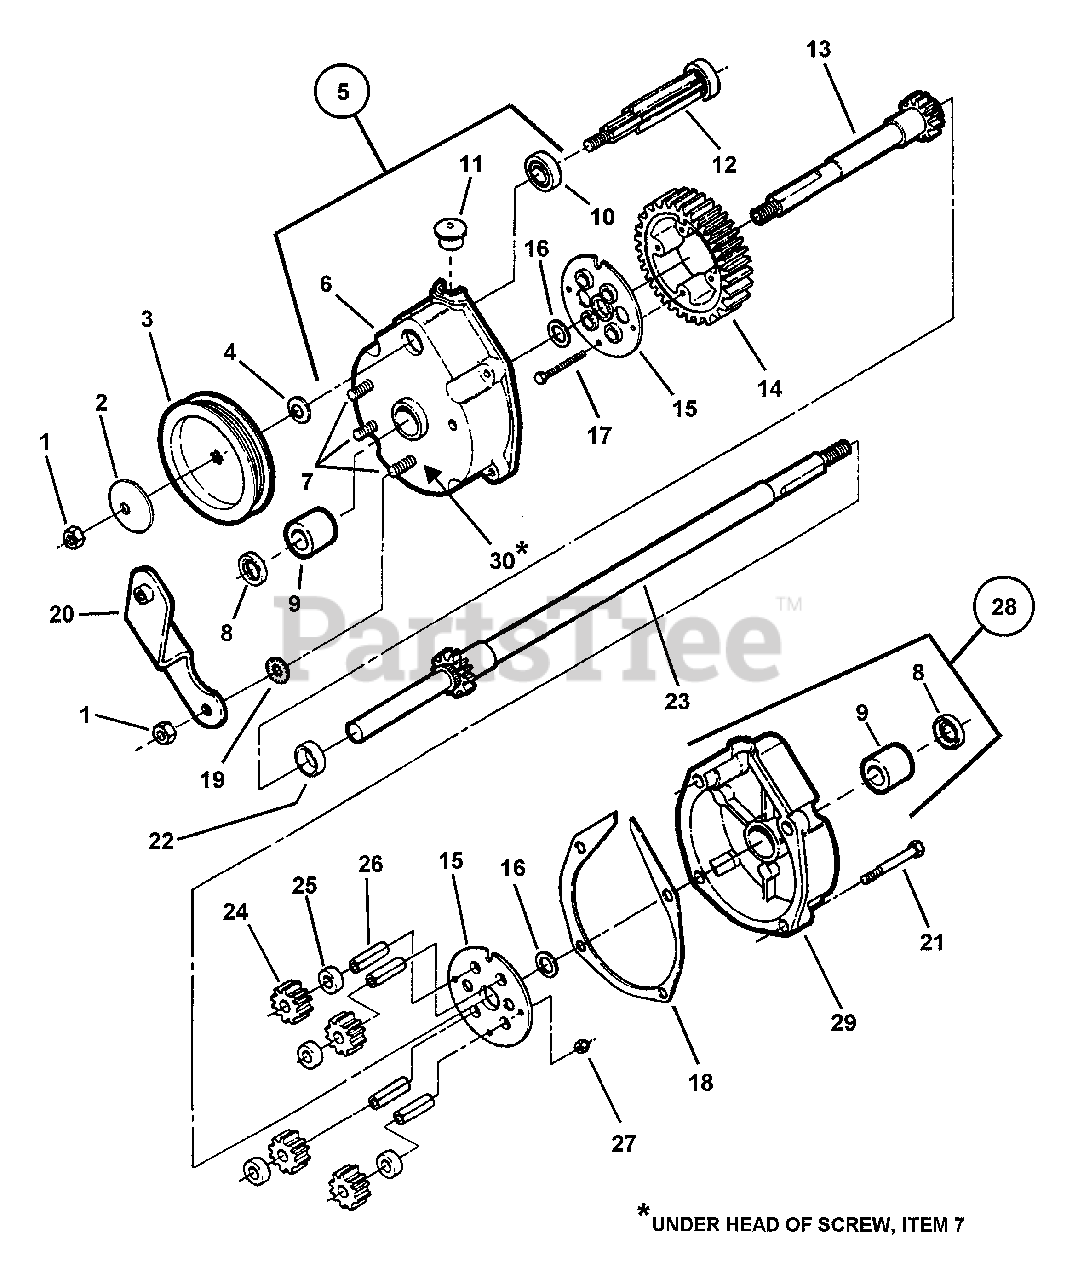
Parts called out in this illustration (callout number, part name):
1	NUT, 5/16-24 Hex Lock, Grade C
2	WASHER, 5/16" I.D. Cone
3	PULLEY, Poly-Vee Belt
4	WASHER, Spring
5	ASSEMBLY, Housing Right
6	HOUSING, Right Side
7	SCREW, 5/16-24 x 1-1/8" Rib Neck, Grade 5
8	SEAL, 5/8 I.D.
9	BEARING, Differential
10	BEARING, Ball
11	PLUG, Housing
12	GEAR, Input
13	AXLE, Short
14	GEAR, Differential (46 Tooth)
15	PLATE
16	WASHER, Thrust
17	SCREW, #10-32 x 1-1/2" Hex Head Cap
18	GASKET, Housing
19	WASHER, 5/16 Internal/External Tooth Lock
20	BRACKET, Differential
21	SCREW, 1/4-20 x 1" Self-Tapping
22	SPACER, Axle Gear
23	AXLE, Long
24	GEAR, Pinion (12 Tooth)
25	SPACER, Pinion Gear
26	SHAFT, Pinion
27	NUT, #10-32 Hex Nyloc
28	ASSEMBLY, Housing Left
29	HOUSING, Left Side
30	GASKET, 5/8" O.D.
